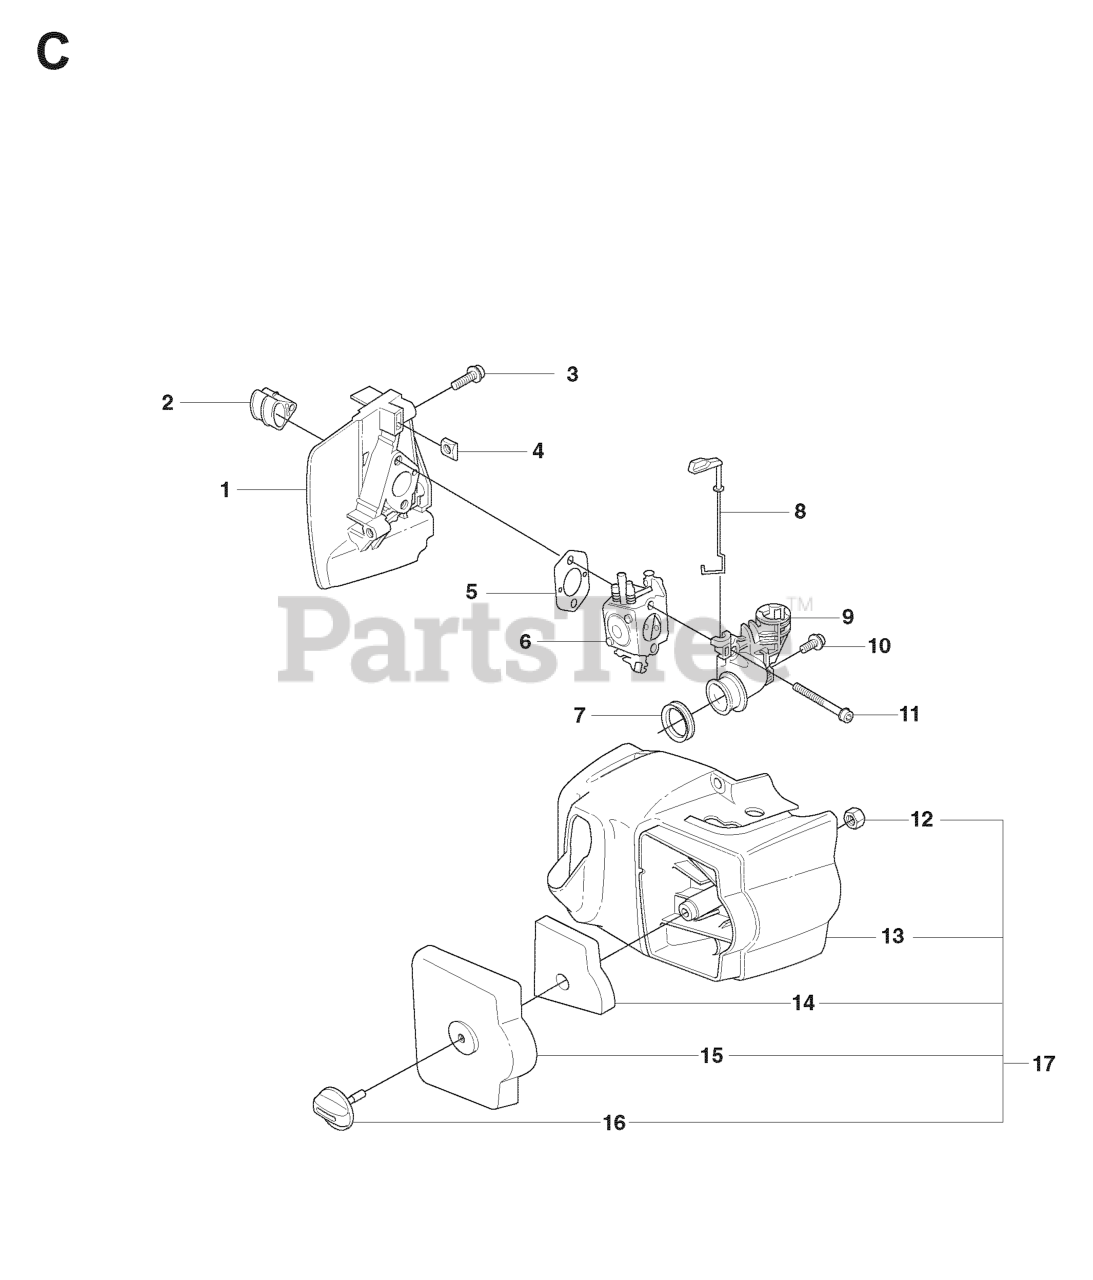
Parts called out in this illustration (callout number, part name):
3	SCREW
6	CARBURETOR
8	CHOKE CONTROL
14	AIR FILTER
15	AIR FILTER COVER
